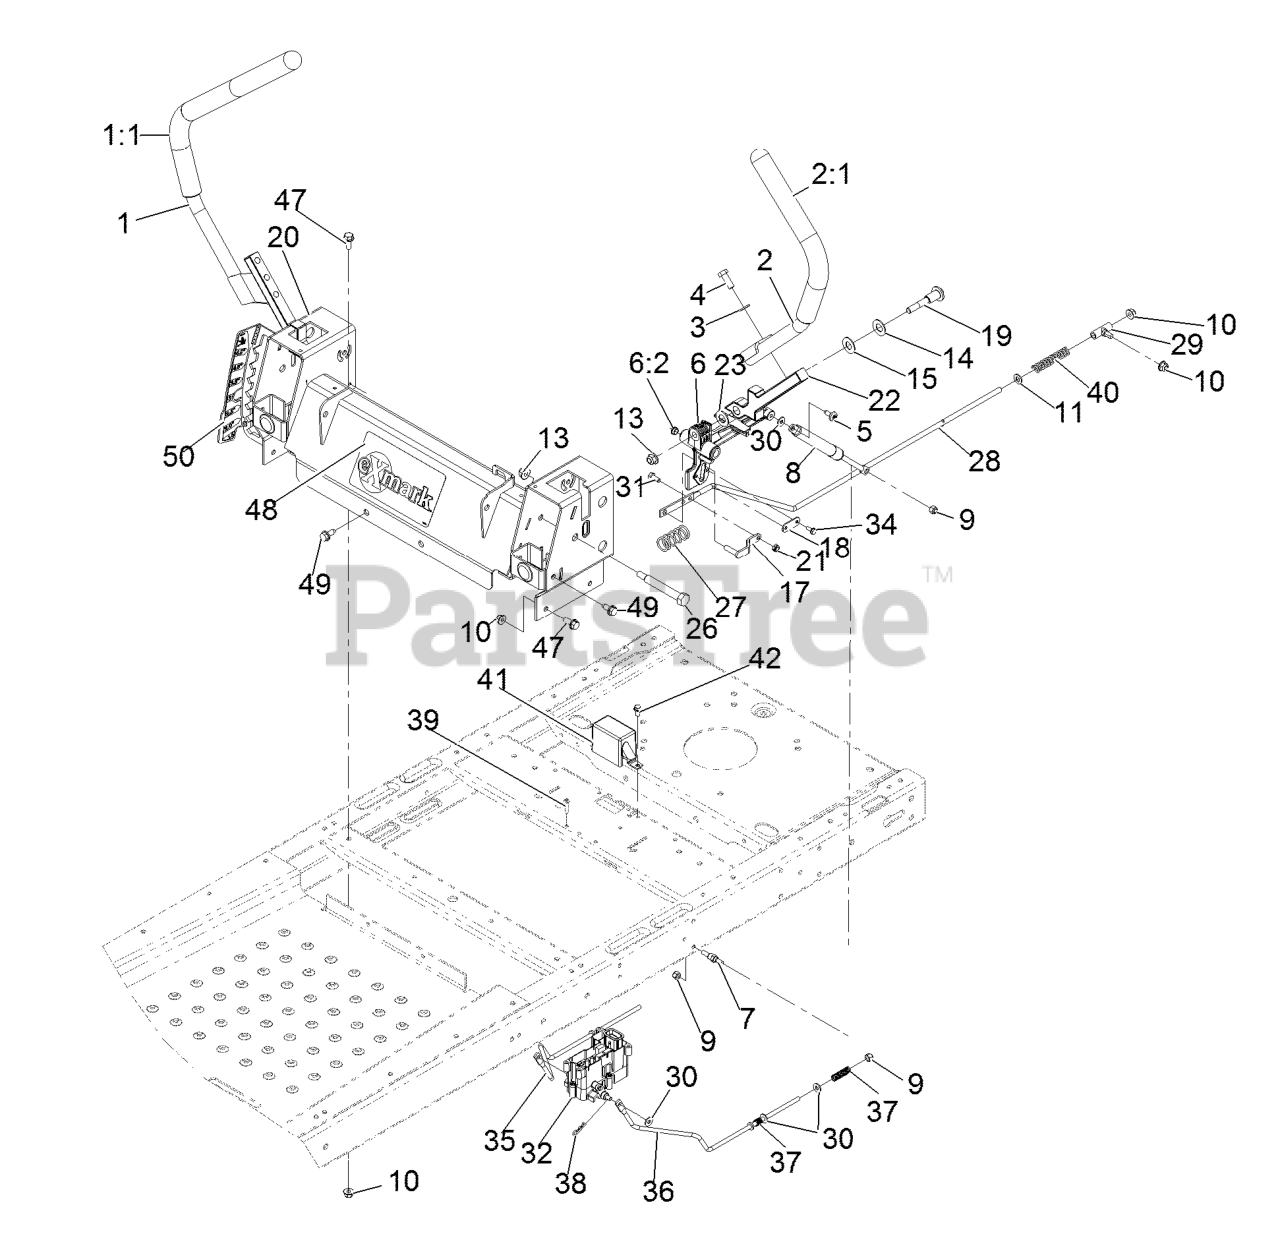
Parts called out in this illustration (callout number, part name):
1	HANDLE-CONTROL, RH
2	HANDLE-CONTROL, LH
3	WASHER-FLAT
4	SCREW-HH
5	SCREW-SHOULDER
6	ACTUATOR ARM ASM
6:2	BUSHING-FLANGE
7	STUD-DAMPER
9	NUT-LOCK, NI
10	NUT-HF, NI
11	WASHER-PLAIN
13	NUT-HF, NI
14	WASHER-BELLEVILLE
18	PLATE-STOP, HYDRO
19	BOLT-PIVOT
20	CONTROL BOX ASM
21	NUT-LOCK, NI
23	WASHER-NYLON
26	BOLT-PIVOT
27	SPRING-RETURN
28	ROD-HYDRO
29	MOUNT-ROD, HYDRO
31	SCREW-HH
34	SCREW-TAPTITE
35	ROD-BRAKE, RH
36	ROD-BRAKE, LH
37	SPRING-COMPRESSION
39	SCREW-PPH
40	SPRING-RETURN, NEUTRAL
41	COVER-BRAKE
42	SCREW-HWH
47	SCREW-HHF
49	Screw-HWH 5/16-18 X 3/4 Tf
50	DECAL-HOC
